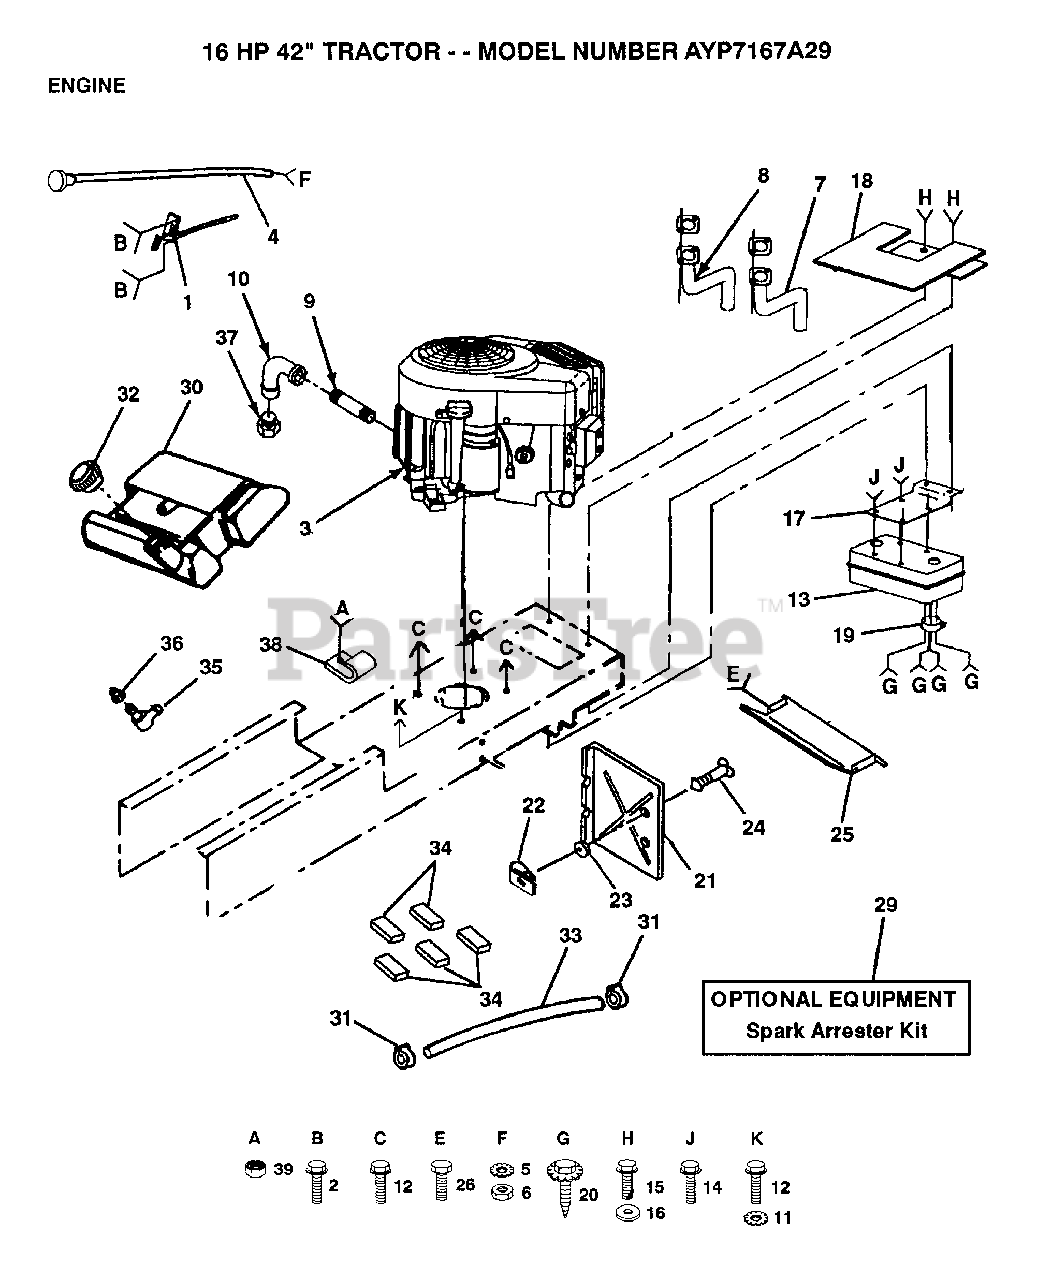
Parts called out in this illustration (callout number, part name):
2	SCREW LT
4	CHOKE CONTROL
5	LOCKWASHER
7	TUBE ASSY EXH RH
8	TUBE ASSY EXH LH
9	PIPE NIPPLE LT
10	ELBOW
11	LOCKWASHER
12	SCREW LT
14	SCREW ST
15	SCREW
16	WASHER
17	BRACKET MUFFLER
19	DEFLECTOR.222573
21	HEAT SHIELD
22	RECEPTACLE LT
23	RETAINER LT
24	STUD.1/4.TURN
25	HEAT SHIELD
26	SCREW
31	HOSE CLAMP
33	FUEL LINE T
34	PAD-SPACER LT
35	BUSHING OUTLET T
36	FUEL TANK STEM GT
38	CLIP T
39	NUT
